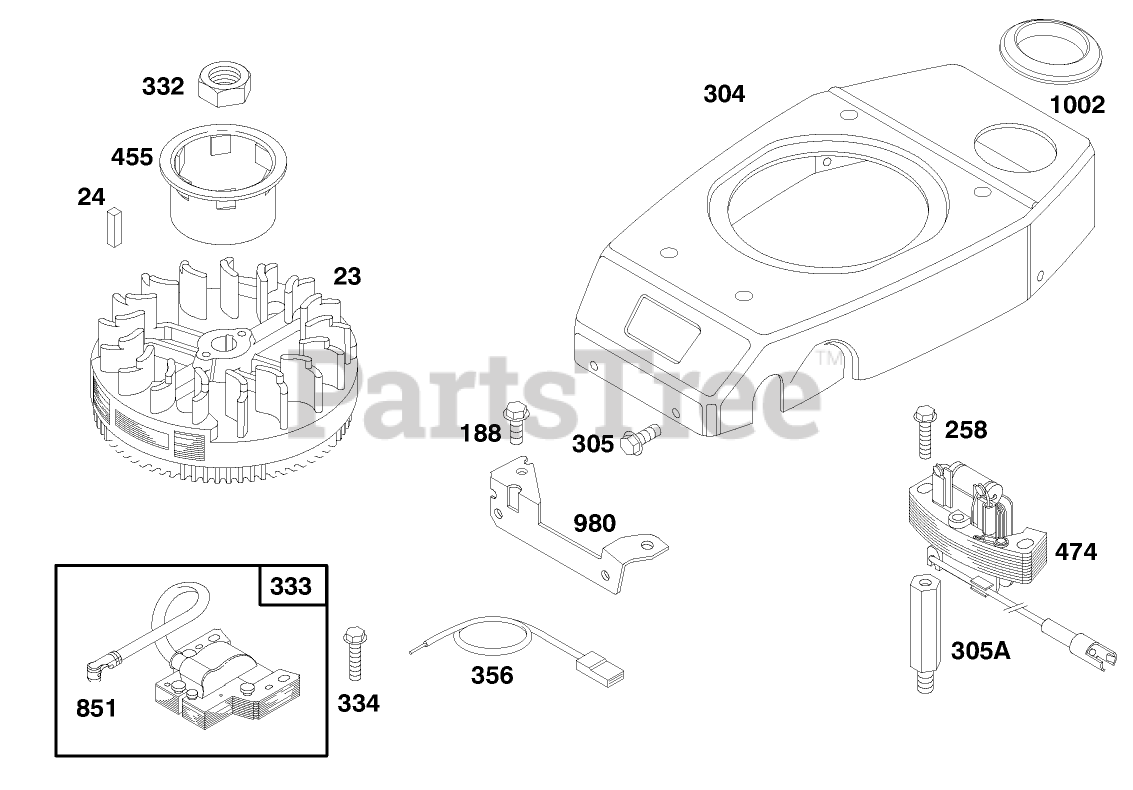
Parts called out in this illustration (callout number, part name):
23	FLYWHEEL - MAGNETO
24	KEY - FLYWHEEL
37	GUARD - FLYWHEEL
305	SCREW - HEX HEAD
332	NUT - HEXAGON
356	WIRE - GROUND
980	BRACKET-BLOWER HSG
